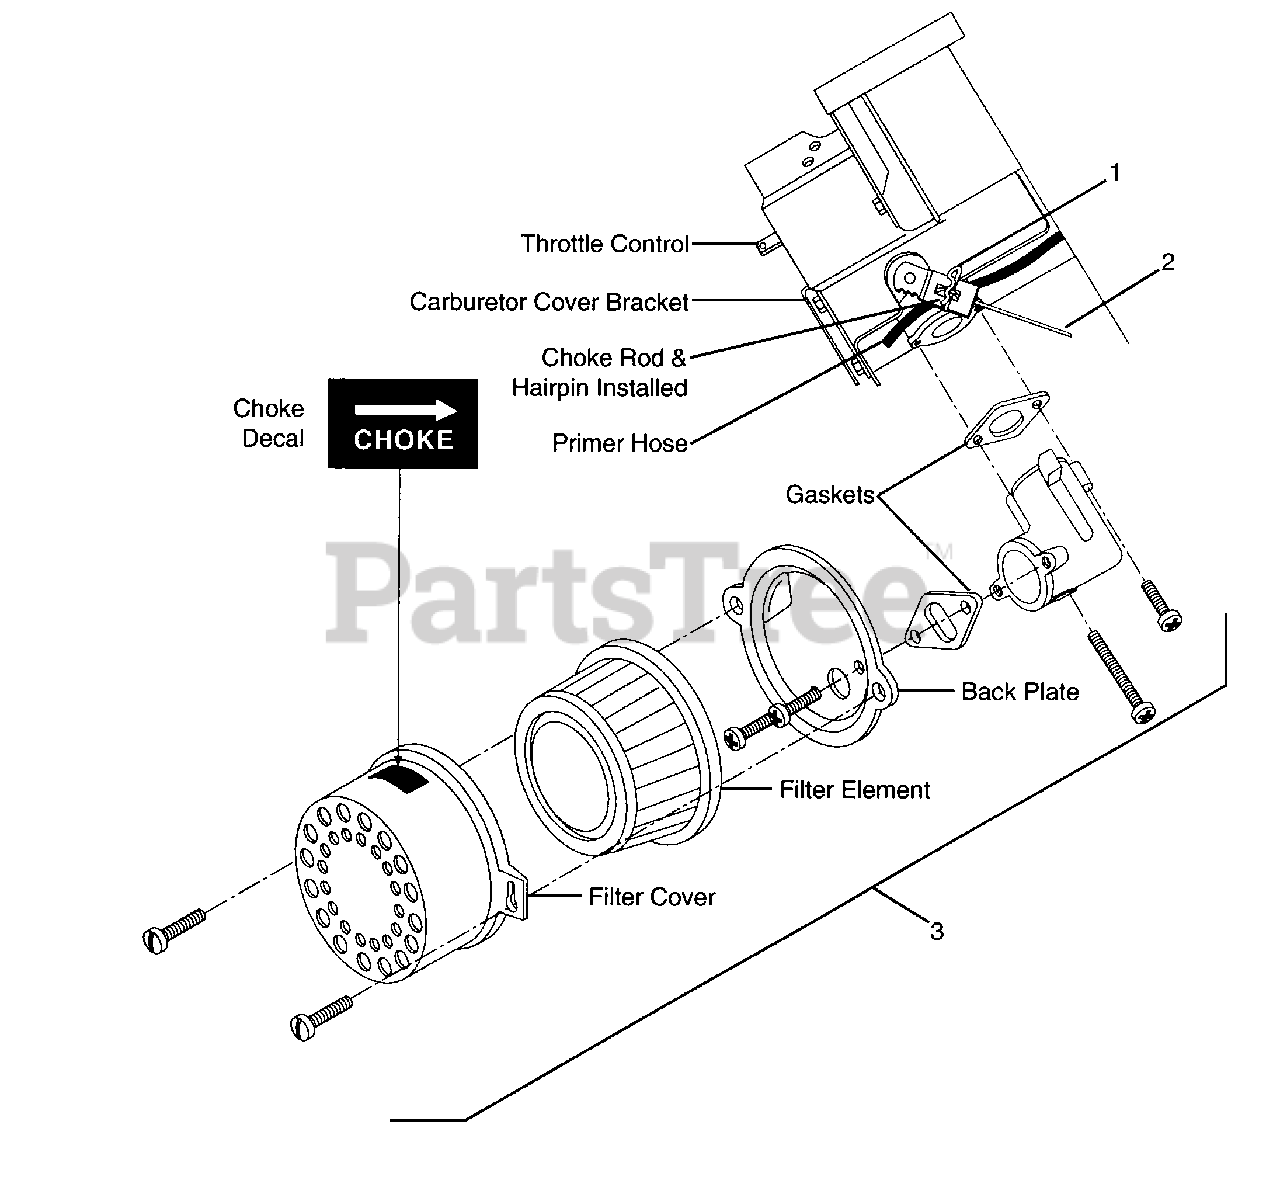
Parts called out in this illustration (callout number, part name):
1	PIN-HAIR INT .06X.18X.77
2	CHOKE ROD
3	AIR CLEANER KIT
